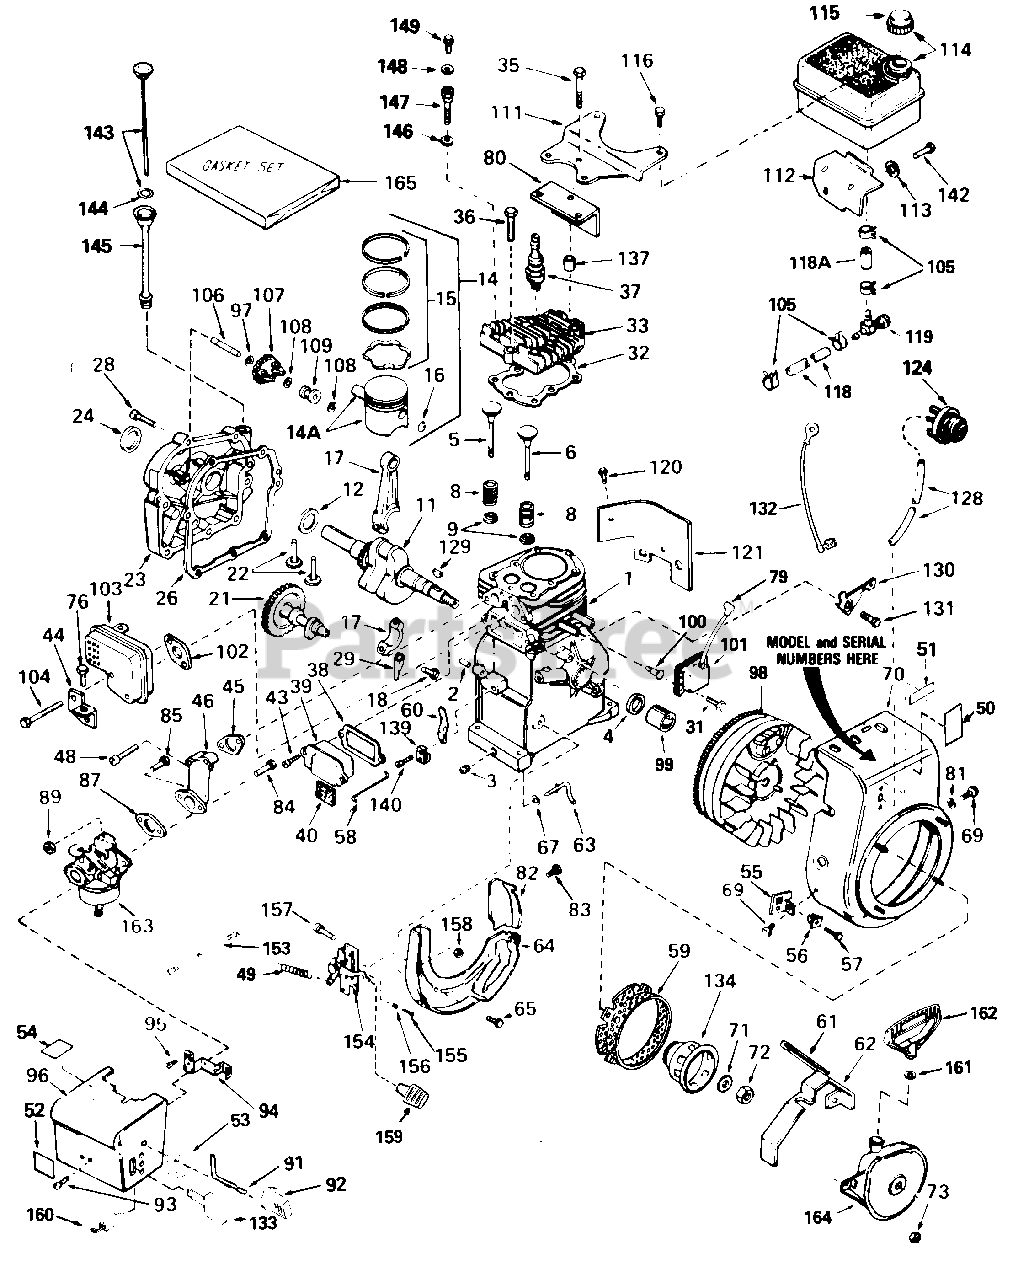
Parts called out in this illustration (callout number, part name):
1	Cylinder Ass'y.
2	Pin, Dowel
3	Plug, Sq. Hd. Pipe, 1/4-18 (Oil Drain)
4	Seal, Oil
5	Valve, Intake (Std.)
6	Valve, Exhaust (Std.)
8	Spring, Valve
9	Cap, Lower Valve Spring
11	Crankshaft Ass'y.
12	Washer, Thrust
14	Piston, Pin & Ring Ass'y. (Std.)
14A	Piston & Pin Ass'y. (Std.)
15	Ring Set, Piston (Std.)
16	Ring, Piston Pin Retaining
17	Rod Ass'y., Connecting
18	Screw, Connecting Rod
21	Camshaft (Compression Release)
22	Lifter, Valve
23	Cover, Cylinder
24	Seal, Oil
26	Gasket, Cylinder Cover
28	Screw, Hex Hd. Sems, 1/4-20 x 1 1/4
29	Dipper, Oil
31	Screw, Hex Hd. Sems, 10-24 x 1
32	Gasket, Cylinder Head
33	Head, Cylinder
35	Screw, Hex Flange Hd., 5/16-18 x 2
36	Screw, Hex Flange Hd., 5/16-18 x 11/2
37	Spark Plug (Champion J-8C or Equivalent)
38	Gasket, Valve Spring Cover
39	Breather Ass'y.
40	Element, Breather
43	Screw, Fil. Hd. Sems, 10-24 x 1/2
44	Bracket, Carburetor Cover
45	Gasket, Intake
46	Pipe, Intake
48	Screw, Fil. Hd. Sems, 1/4-20 x 1-19/32
49	Spring, Extension
50	Decal, Name
51	Decal, Primer (Bilingual)
52	Decal, Instruction
53	Decal, Instruction (Bilingual)
54	Decal, Warning (Bilingual)
55	Bracket, Grommet Mounting
56	Grommet, Plastic
57	Screw, Pan Hd. Self-Tap, 8-18 x 3/8
58	Link, Governor-to-Throttle
59	Screen, Starter Cup
60	Lever, Governor
61	Seal, Snow Guard
62	Guard, Starter
63	Rod Governor
64	Baffle, Blower Housing
65	Screw, Hex Washer Hd. Durlok, 1/4-20 x 5/8
67	Washer, Flat
69	Screw, Hex Hd. Sems, 1/4-28 x 7/16
70	Housing, Blower
71	Washer, Belleville
72	Nut, Flywheel
73	Nut & Lockwasher Assy'., 1/4-28
76	Screw, Hex Hd. Sems Taptite, 10-24 x 3/8
79	Cover, Spark Plug
80	Baffle, Heat
81	Washer, Flat
82	Extension, Baffle
83	Screw, Hex Washer Hd. Shakeproof Self-Drilling, 8-18 x 7/16
84	Screw, Hex Hd., 1/4-28 x 7/8
85	Screw, Hex Hd., 1/4-28 x 1-11/16
87	Gasket, Carburetor
89	Nut & Lockwasher Ass'y., 1/4-28
91	Rod, Choke
92	Knob, Choke
93	Screw, Pan Hd. Sems, 8-32 x 5/16
94	Bracket, Choke
95	Screw, Fil. Hd. Sems, 10-32 x 1/2
96	Cover, Carburetor
97	Washer, Flat
98	Flywheel (w/Ring Gear)
99	Spacer, Flywheel
100	Stud, Solid State
101	Solid State Ass'y.
102	Gasket, Muffler
103	Muffler
104	Screw, Fil. Hd. Sems, 1/4-20 x 21/2
105	Clamp, Fuel Line
106	Shaft, Mechanical Governor
107	Gear Ass'y., Governor
108	Ring, Retaining
109	Spool, Governor
111	Bracket, Fuel Tank-Upper
112	Bracket, Fuel Tank-Lower
113	Washer, Flat
114	Tank Ass'y., Fuel
115	Cap, Fuel Tank
116	Screw, Hex Washer Hd. Sems, Self-Tap, 1/4-14 x 718
118	Line, Fuel
118A	Line, Fuel
119	Valve, Fuel Shut-Off
120	Screw, Fil. Hd. Sems, 10-24 x 1/2
121	Extension, Blower Housing
124	Primer Ass'y.
128	Line, Primer
129	Key, Flywheel
130	Bracket, Hold Down
131	Screw, Hex Washer Hd. Self-Tap Sems, 10-24 x 9/16
132	Wire, Ground
133	Key, Ignition
134	Cup, Starter
139	Clamp, Governor Lever
140	Screw, Hex Washer Hd., 8-32 x 5/16
142	Screw, Hex Hd. w/Belleville Washer, 1/4-20 x 11/16
143	Dipstick
145	Tube, Oil Fill
146	Washer, Flat
147	Screw, Special Hex Hd., 5/16-18x1-l/2
148	Washer, Flat
149	Screw, Hex Hd., Sems, 1/4-20 X 1/2
153	Wire, Ground
154	Control Ass'y., Speed
155	Screw, Fil. Hd., 5-40 x 7/16
156	Spring, Compression
157	Screw, Fil. Hd. Sems, 8-32 x 1/2
158	Locknut, Hex "Keps," 8-32
159	Knob, Control
160	Terminal Ass'y.
161	Washer, Flat
162	Handle, Starter (Mitten Grip)
163	Carburetor
164	Starter Ass'y., Rewind
165	Gasket Set
